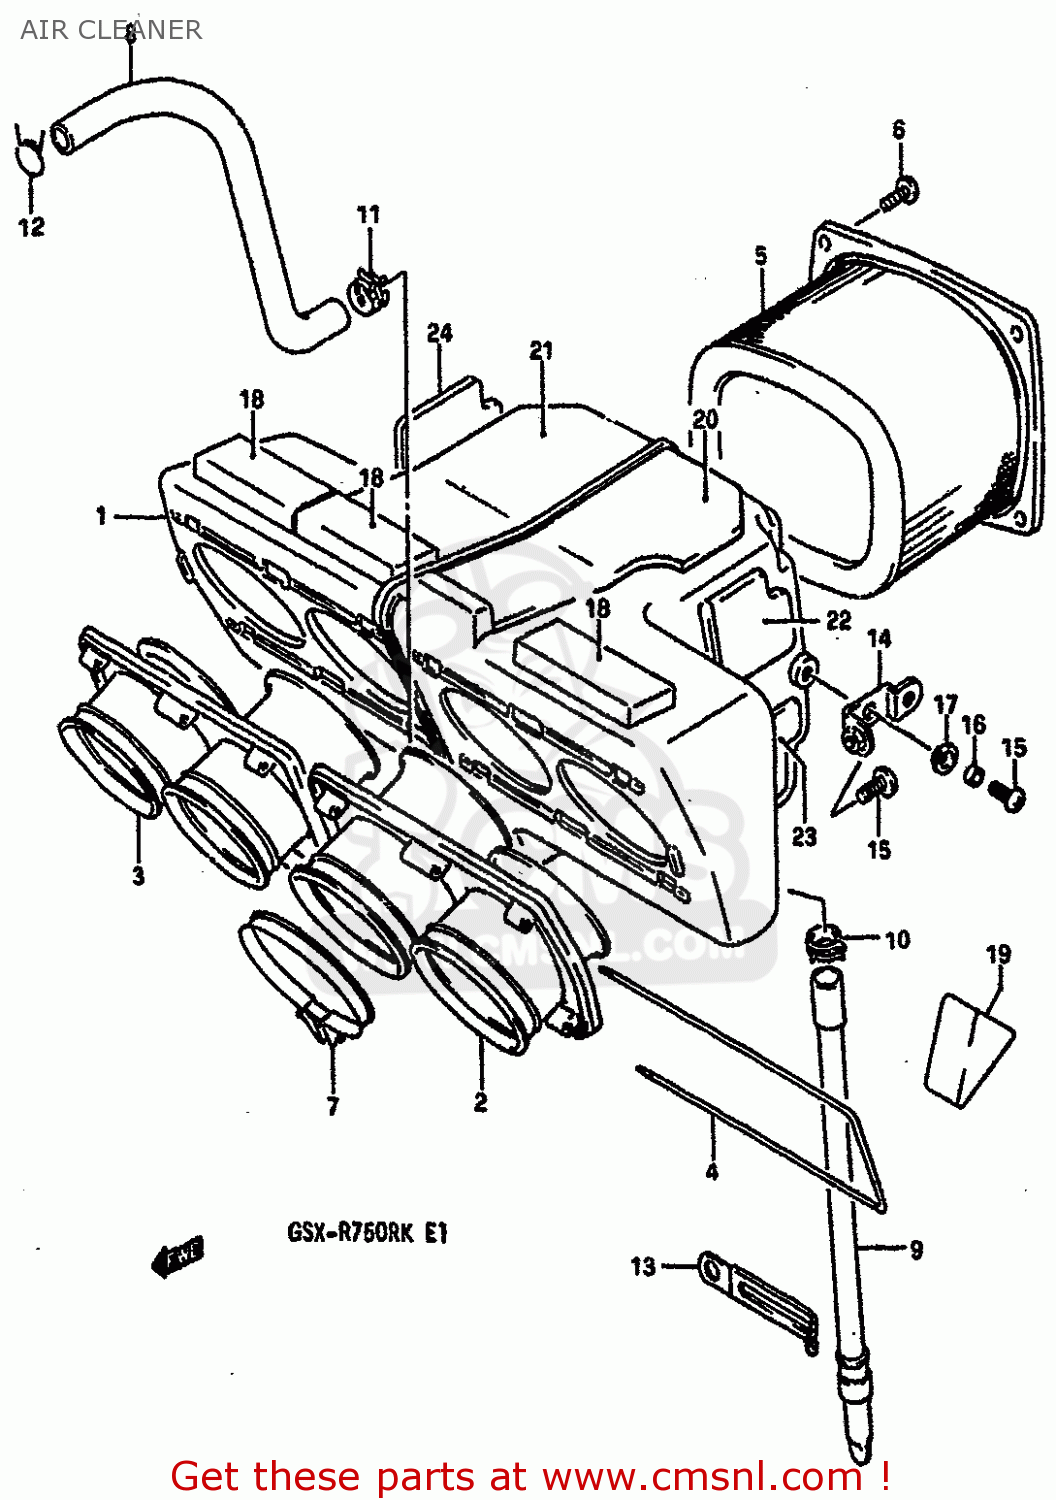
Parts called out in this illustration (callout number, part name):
1	CASE,AIR CLEANER
2	TUBE,OUTLET,L
3	TUBE,OUTLET,R
4	SHAFT,OUTLET TUBE
5	FILTER ASSY,AIR CLEANER
6	SCREW
7	CLAMP
8	TUBE,BREATHER
9	DRAIN TUBE
10	CLIP
11	CLIP
12	CLIP
13	CLAMP
14	BRACKET,AIR CLEANER CASE
15	SCREW
16	SPACER
17	WASHER
18	CUSHION,AIR CLEANER CASE
19	CUSHION,AIR VENT HOSE
20	SHEET,AIR CLEANER NO.1
21	SHEET,AIR CLEANER NO.2
22	SHEET,AIR CLEANER NO.3
23	SHEET,AIR CLEANER NO.4
24	SHEET,AIR CLEANER NO.5
